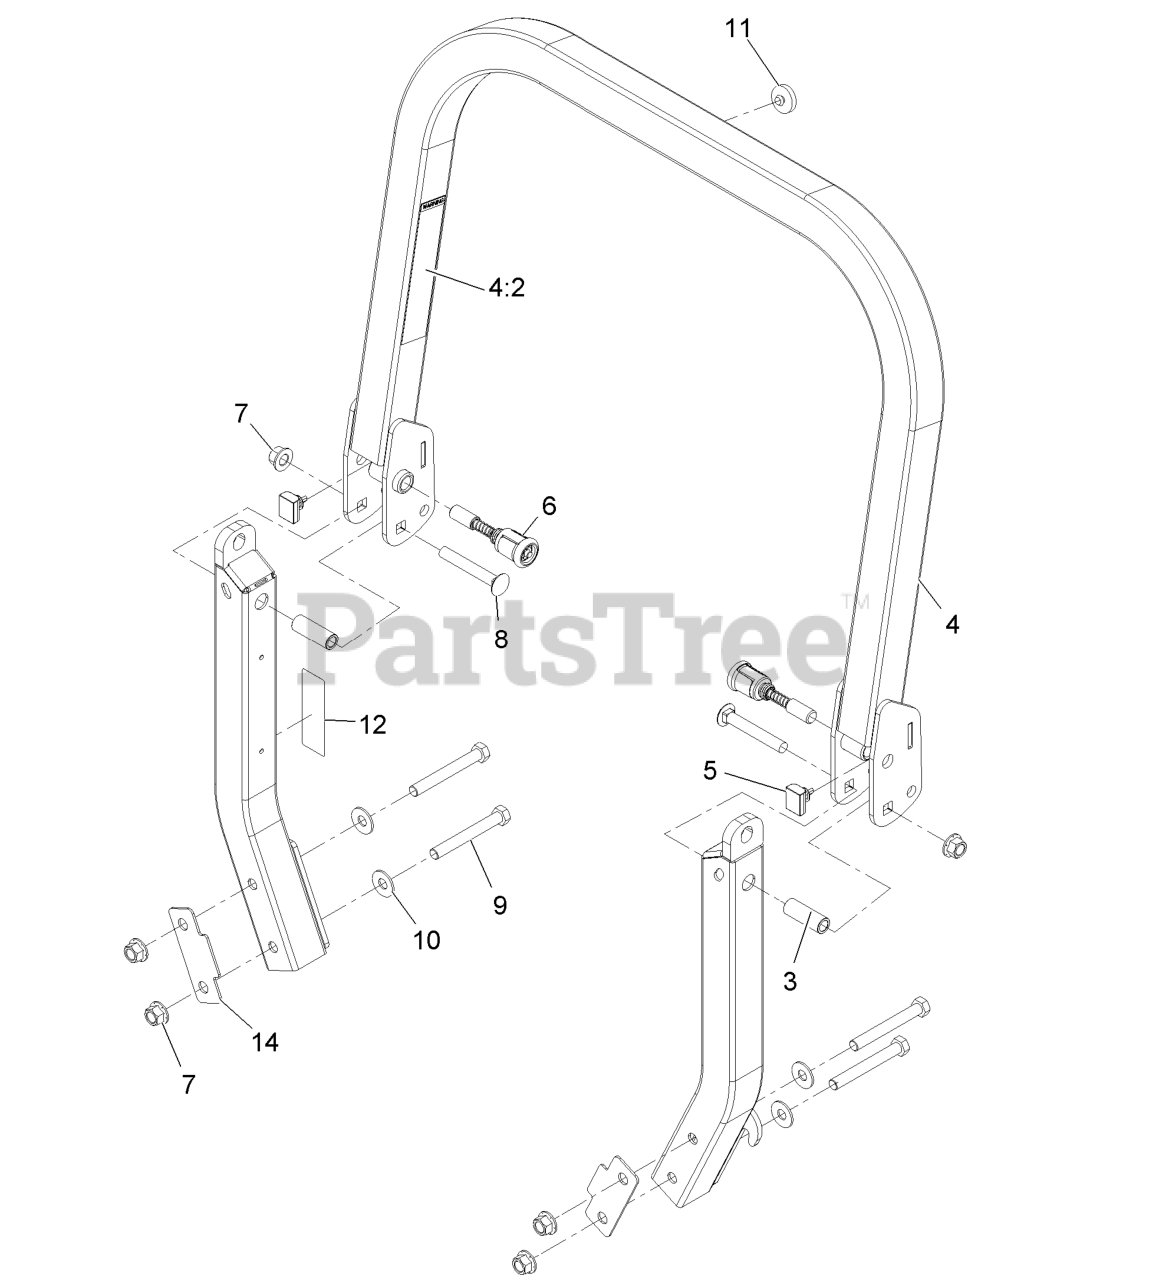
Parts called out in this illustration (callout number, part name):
4	UPPER ROPS ASM
4:2	DECAL-WARNING, FOLDING RO
5	BUMPER-ROPS
6	PIN-SPRING
7	Nut-Lock 1/2-13
8	SCREW-CARR
9	SCREW-HH
10	WASHER-SPRING
11	BUMPER-PUSH-IN, RUBBER
12	DECAL-CAUTION
